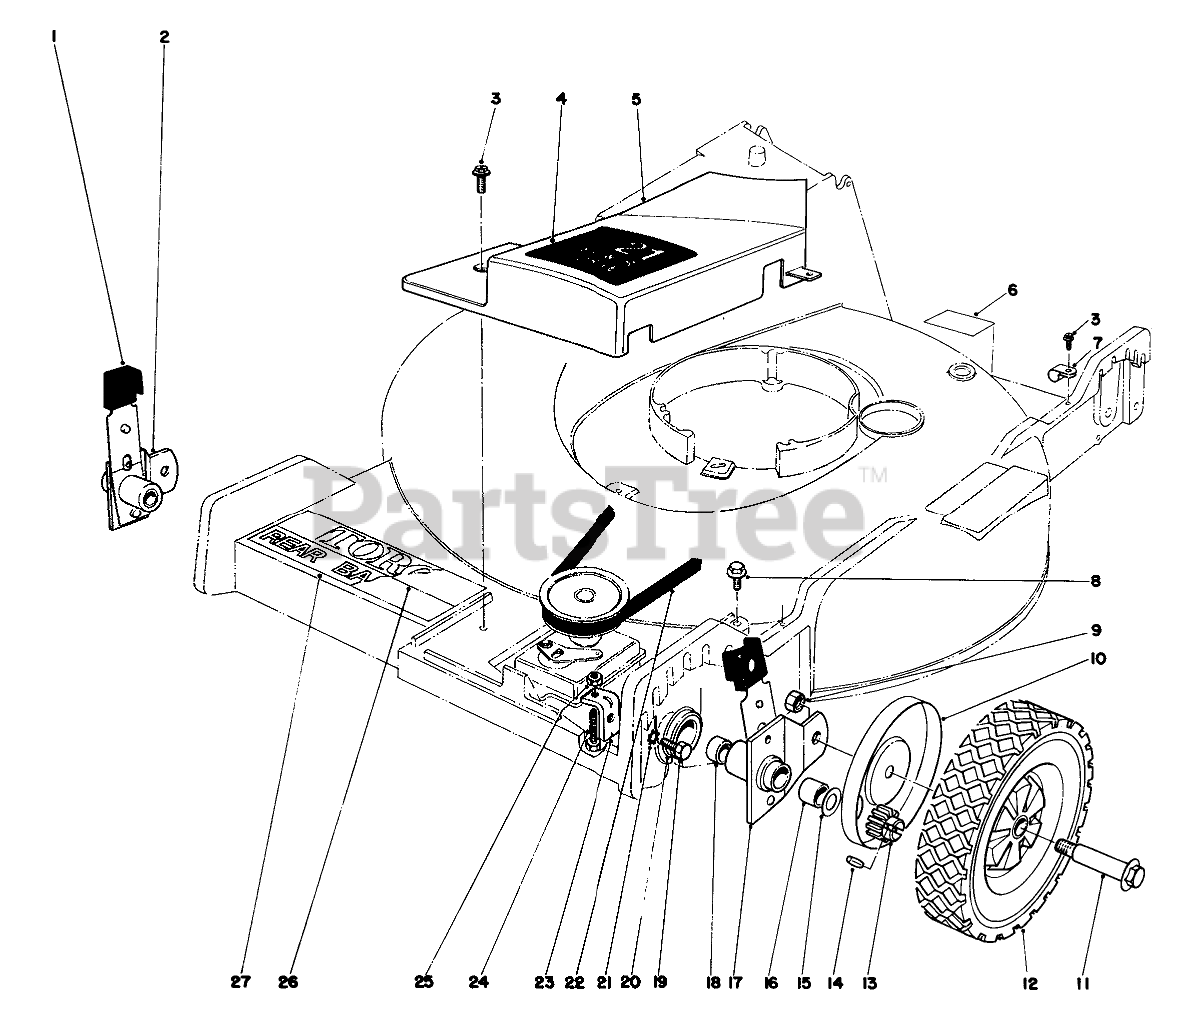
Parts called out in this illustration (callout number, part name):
1	KNOB-ARM
2	Pivot Arm R. H. (Incl. Ref. #16 & 18)
3	SCREW
4	Decal Belt Cover
5	BELT COVER
6	Greasing Sticker
7	CLAMP-NYLON
8	SCREW-HWHTF
9	Nut
10	WHEEL COVER
11	BOLT-WHEEL
12	Wheel & Tire Assembly
13	Pinion
14	PIN-GROOVED
15	WASHER-THRUST
16	Bushing
17	Pivot Arm L.H. (Incl. Ref. #16 & 18)
18	Bushing
19	SCREW-HH
20	END CAP
21	WASHER-LOCK
22	V-BELT
23	Bracket-Gear Box
24	SCREW
25	NUT-LOCK
26	TORO LOGO DECAL
27	DECK DECAL
